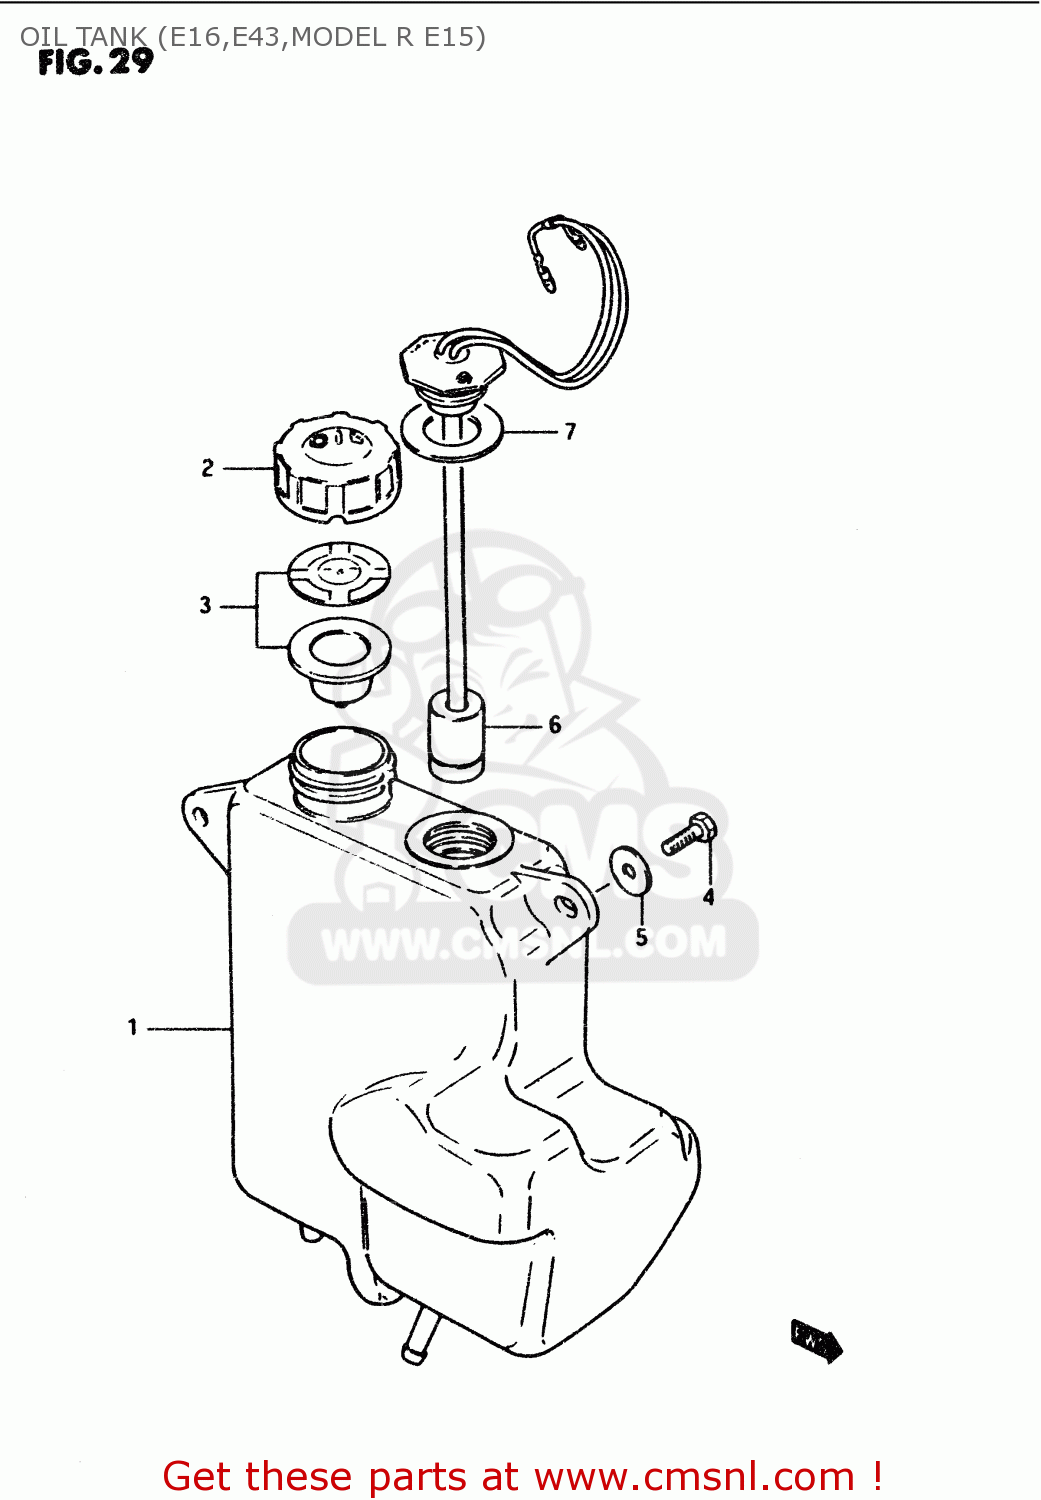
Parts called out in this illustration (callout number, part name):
1	TANK,OIL
2	CAP,OIL TANK
3	GASKET SET (NAS)
4	BOLT
5	WASHER
6	SWITCH ASSY, OIL LEVEL
7	GASKET (NAS)
